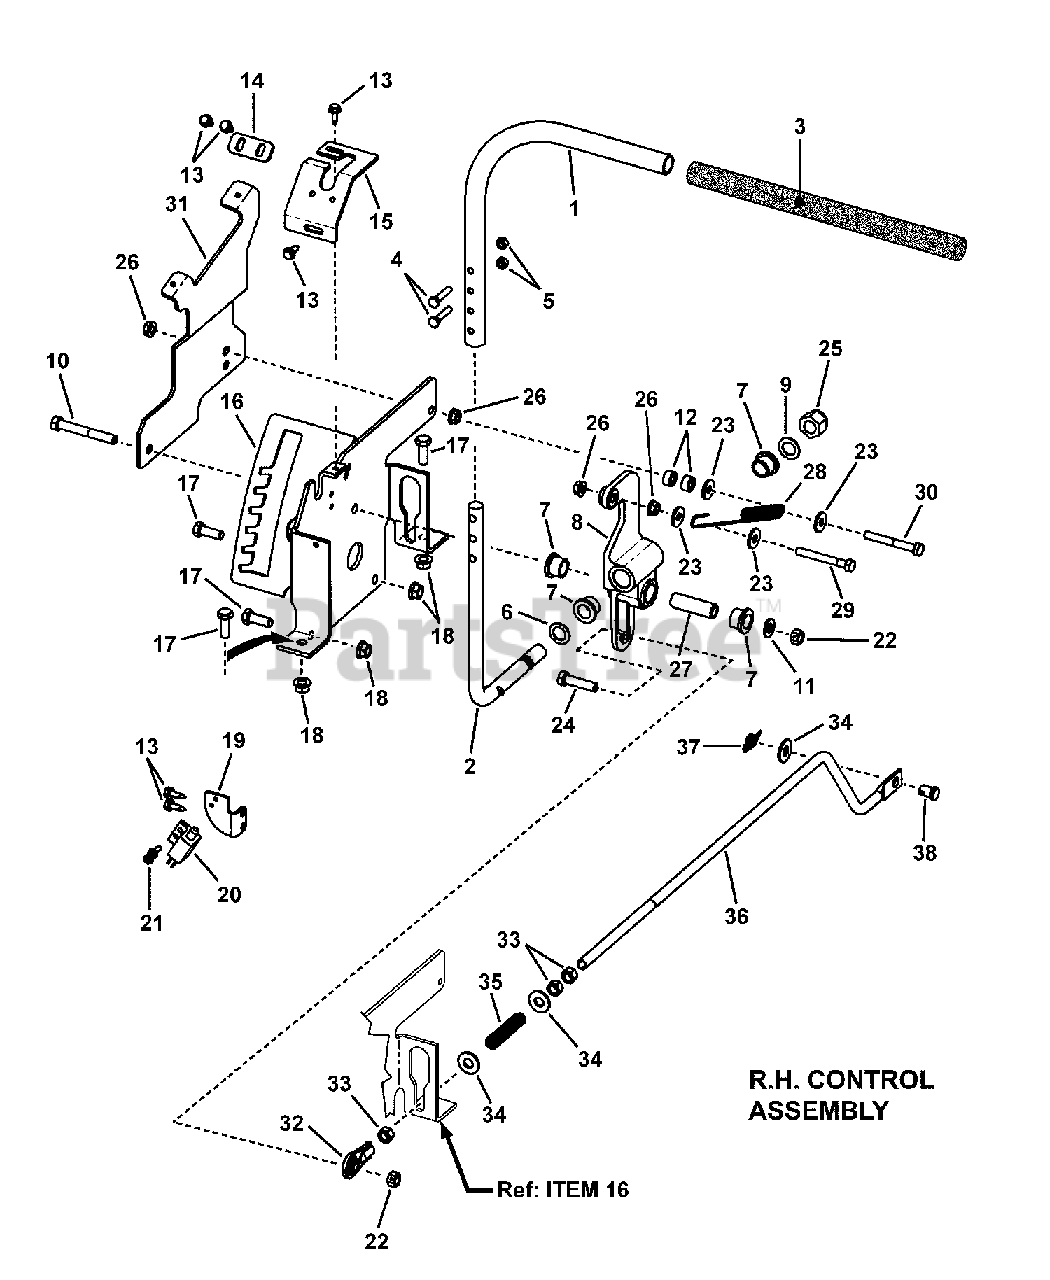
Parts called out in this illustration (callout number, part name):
1	HANDLE
2	ROD, Handle R.H. (5/8" dia. Rod)
3	FOAM GRIP, Handle
4	SCREW, 1/4-20 x 1-1/4" Hex Head Cap, GR 5
5	NUT 1/4-20 Hex Center Lock, GR 5 YZ
6	WASHER, .64 x .99 x .05 Flat, YZ
7	BUSHING, Bronze, 5/8 x 5/8"
8	CONTROL ARM, RH Die Cast
9	WASHER, 5/8 ID x 1.00 OD x .065 Nylon
10	SCREW, 3/8-16 x 2-3/4" Hex Head Cap, GR 5
11	WASHER, 3/8" Flat SAE
12	SPACER, .34 x .63 x .31
13	SCREW, 1/4-20 x 3/4" Hex Washer Self-Tap
14	PLATE, Fwd/Rev Adjust
15	TRACK, Control Stick, R.H.
16	WELDMENT, Lift Bracket
17	SCREW, 3/8-16 x 1" Hex Head Cap, GR 5, YZ
18	NUT, 3/8-16 Hex Flange Lock
19	BRACKET, Switch
20	SWITCH, Single Pole, LG-1, NC
21	SCREW, #10-24 x 1/2" Hex Washer Self-Tap (Torx)
22	NUT, 3/8-16 Hex Center Lock, GR 5 or B, YZ
23	WASHER, .33 x .88 x .09 Flat
24	SCREW, 3/8-16 x 1-1/2" Hex Head Cap, GR 5
25	NUT, 5/8-18 Hex Nyloc
26	NUT, 5/16-18 Hex Flange Lock, GR 5
27	SPACER, Motor
28	SPRING, Extension, RTN, ERZT
29	SCREW, 5/16-18 x 2-3/4" Hex Head Cap, GR 5
30	SCREW, 5/16-18 x 2-1/2" Hex Head Cap, GR 5
31	BRACKET, Fender Support, RH
32	ROD END
33	NUT, 3/8-24 Hex, GR B, YZ
34	WASHER, 7/16" Flat
35	SPRING, Compression (Brake)
36	ROD, Link Fwd./Rev. (3/8-24 thread)
37	COTTER PIN, 1/2 Self Locking, YZ
38	CLEVIS PIN, 7/16 x 1"
